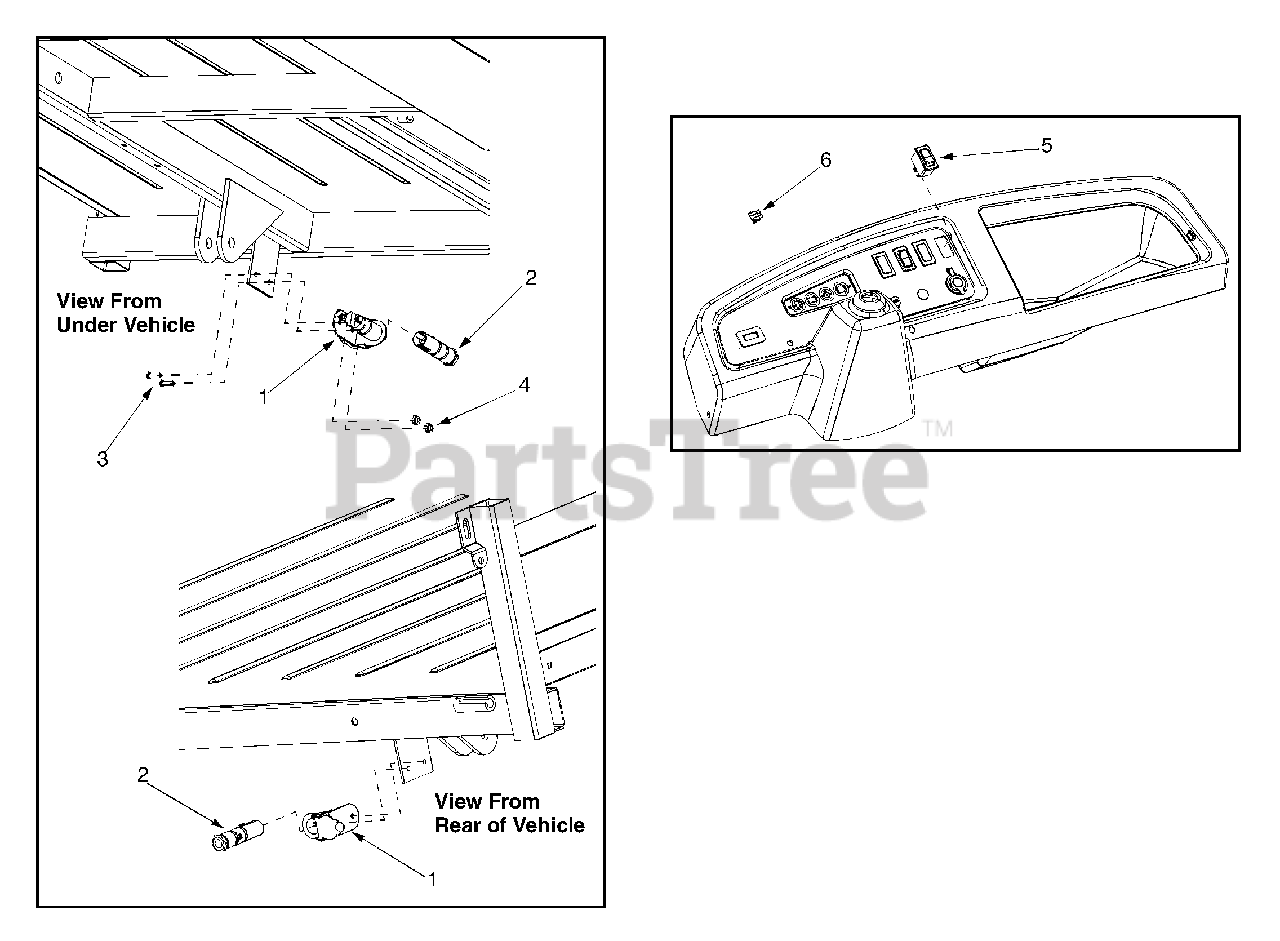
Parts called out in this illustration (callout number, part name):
1	Power Reciprocal
2	Plug Reciprocal
3	Machine Screw 10-32 x .50
4	Hex Lock Nut #10-32
5	Power Switch
6	Fuse 15 amp
